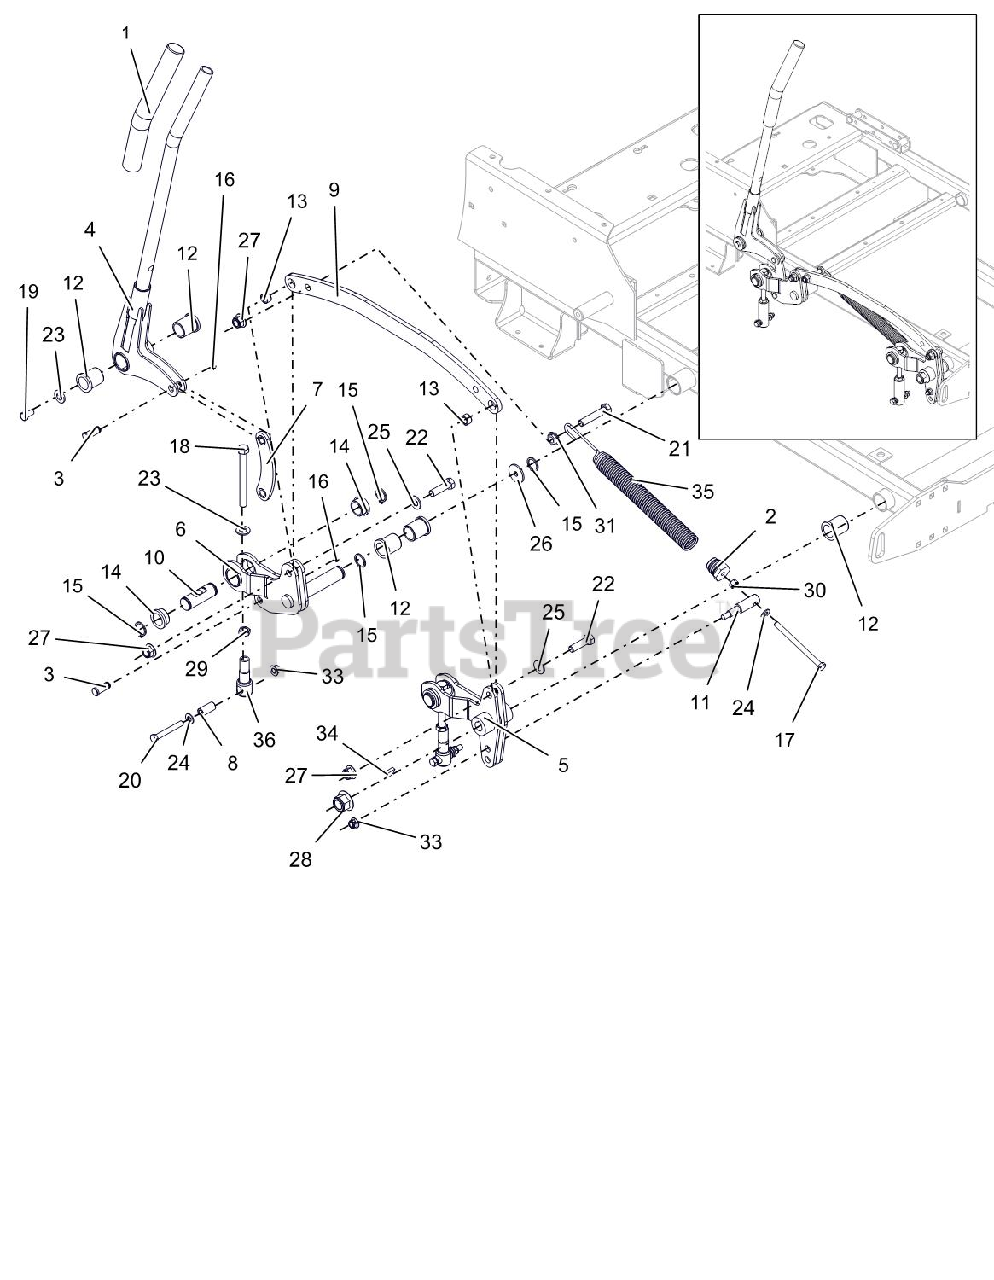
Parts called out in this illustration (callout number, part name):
1	GRIP, HANDLEBAR 1.00X1.38X11.3
2	PLUG, SPRING
3	PIN, CLEVIS .500 SNAP RING
4	WLDMT, HAND LEVER
5	WLDMT, PSTANCE TAPERED HUB
6	WLDMT, PSTANCE DECK ARM
7	WLDMT, DECK LIFT LINK
8	SPACER, DECK LEVELING
9	ARM, DECK LIFT
10	PIN, DECK LIFT
11	TRUNION, DECK LIFT
12	BSHG-FLG 1.00X1.25X1.50X1.50
13	BSHG-SLV .513 X .748 X .420
14	BSHG,FLG 1.0 X 1.25 X 1.5 X .6
15	RG-RTNG-EXT 1.00X.078
16	RG-RTNG-EXT .500X.050 (SNAP)
17	BLT-HEX .38-16X5.00 GR5 FTH YZ
18	BOLT, 1/2-13 X 5.0 2.5 THREAD
19	@BLT-HEX .38-16X.75 GR5 YWZC
20	BLT-HEX .38-16X2.75 GR8 YWZC
21	@BLT-HEX .50-13X2.50 GR5 YWZC
22	@BLT-HEX .50-13X1.75 GR5 YWZC
23	FLATWASHER 1/2 SAE HARD 15906
24	@WSHR-FL-STL.406X.812X.065 YWZ
25	@WSHR-FL-STL.531X1.06X.095YWZC
26	WSHR-FL-STL .380X1.50X.125YWZC
27	@NUT-LK-NYL-FLG .50-13 YWZC
28	@NUT-LK-NYL-FLG .75-10 YWZC
29	NUT-JAM .50-13 YWZC
30	@NUT-HEX .38-16 YWZC
31	NUT-SPNLK-FLG .50-13 YWZC
33	@NUT-LK-NYL-FLG .38-16 YWZC
34	KEY-WDRF .25X1.00 HRD #15
35	SPRING, DECK LIFT
36	LINK, DECK LIFT FORMED
